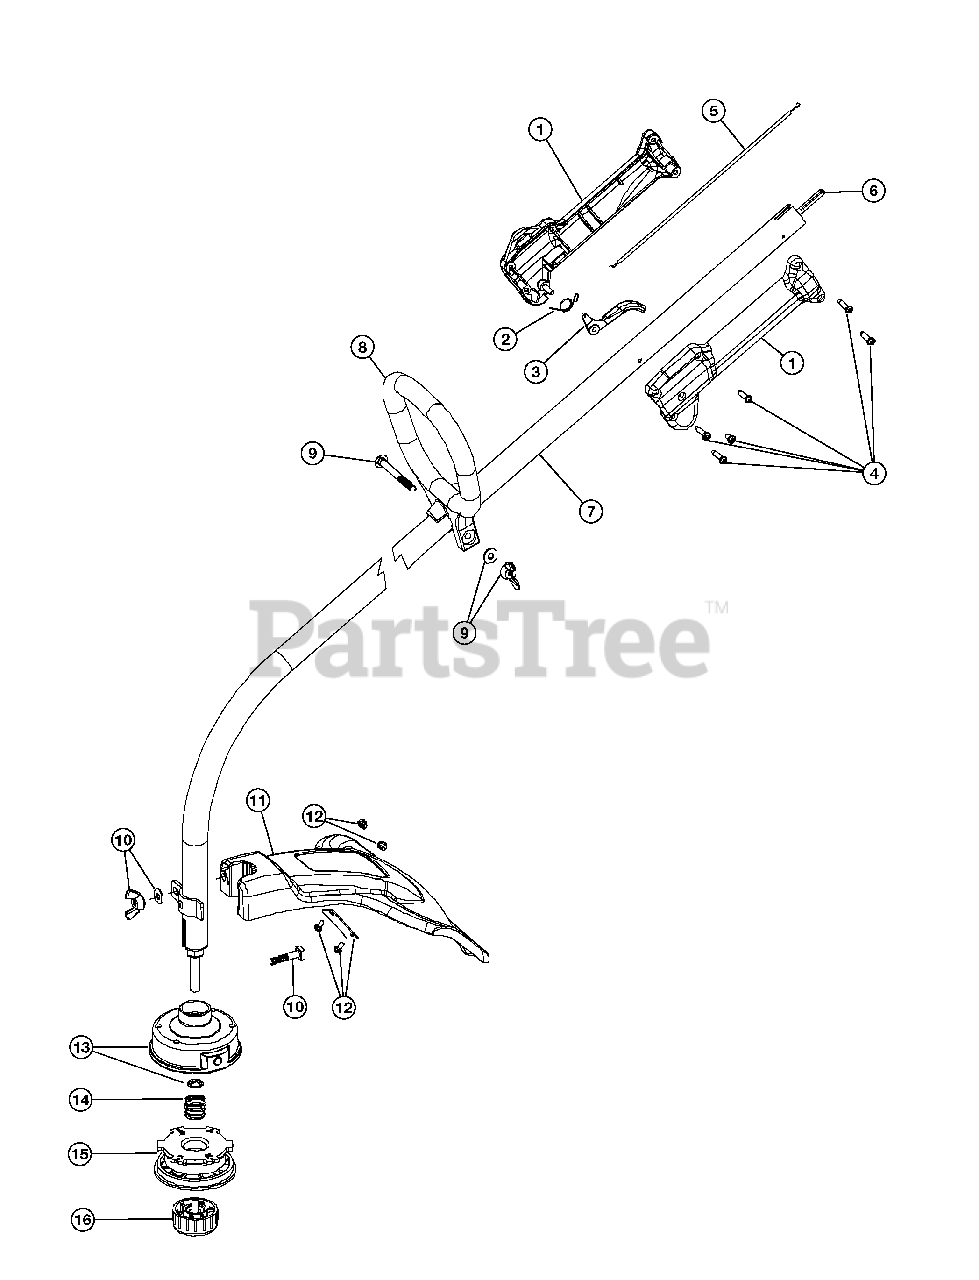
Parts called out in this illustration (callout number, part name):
1	Throttle Housing and Trigger Assembly
2	Throttle Trigger Spring
3	Throttle Trigger
4	Throttle Housing Screws
5	Throttle Cable
6	Flexible Drive Shaft
7	Drive Shaft Housing Assembly
8	D-Handle Assembly
9	D-Handle Hardware
10	Guard Mounting Hardware
12	Blade Assembly
13	Outer Reel w/Retainer
14	Spring
15	Inner Reel
16	Bump Knob
